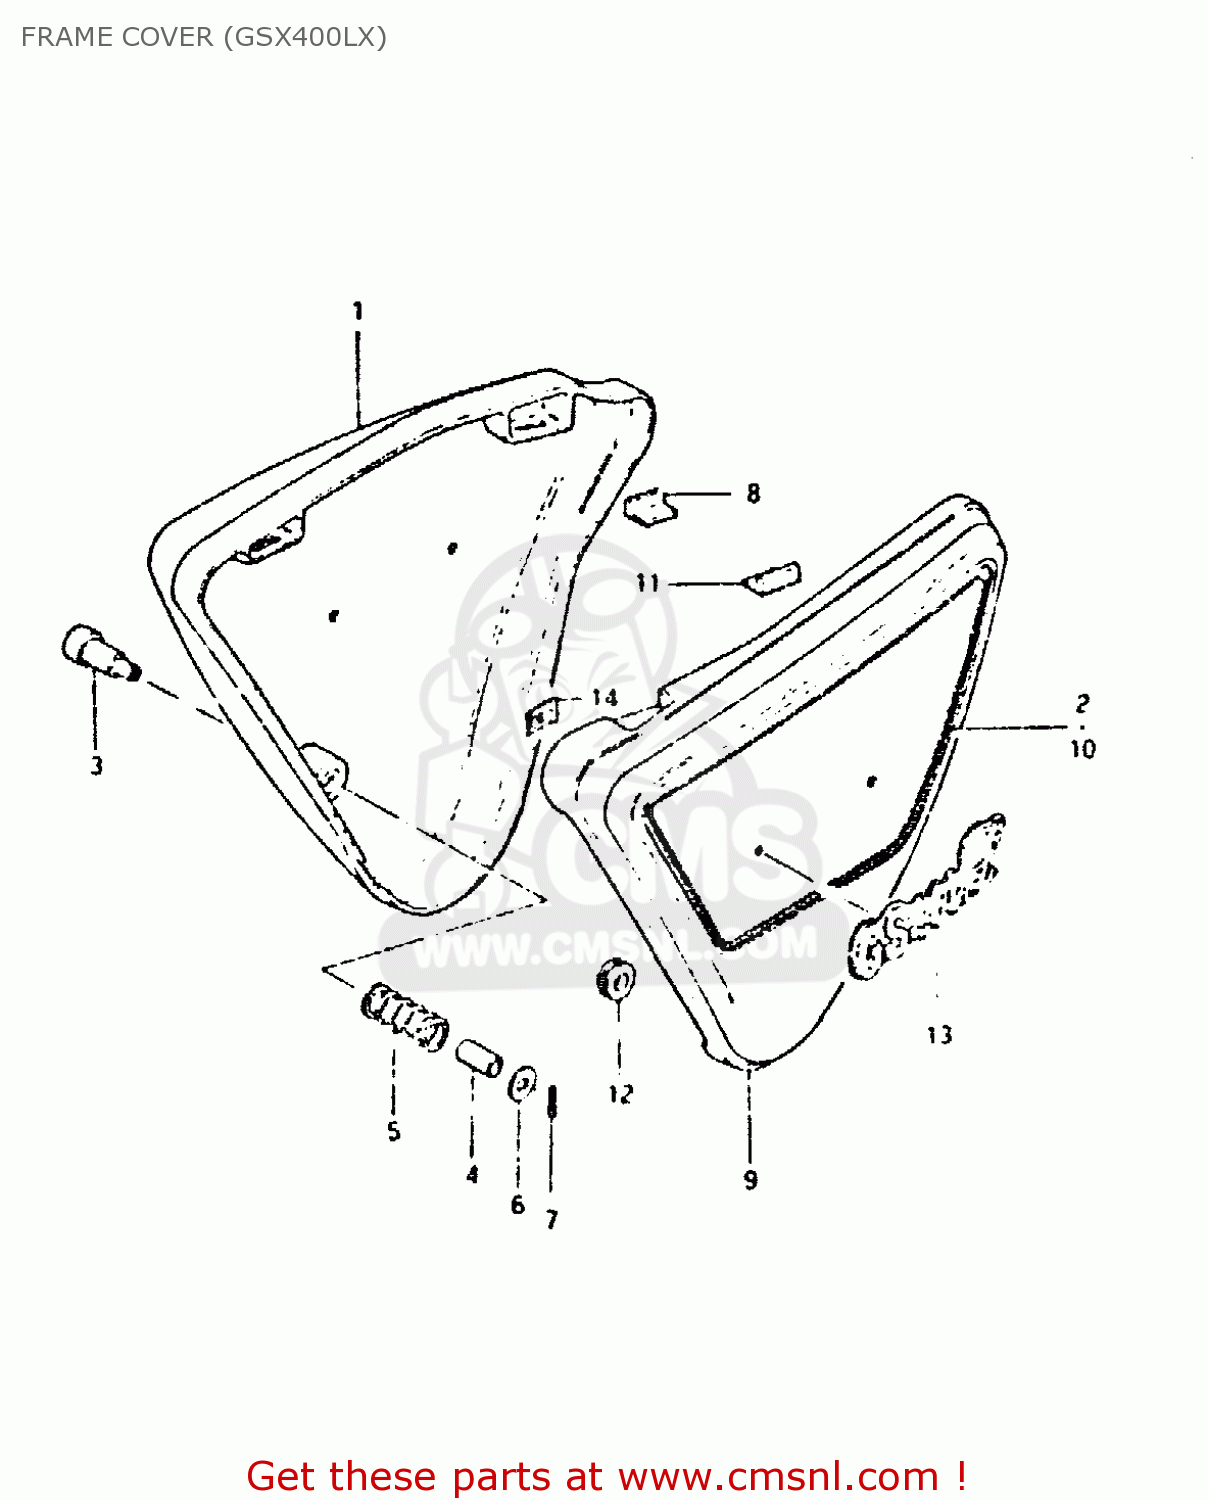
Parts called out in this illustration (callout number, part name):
1	COVER,FRAME,RIGHT
2	TAPE SET,FRAME COVER,RIGHT
3	KNOB,FRAME COVER
4	SPACER(14.9X17.3X13.5)
5	SPRING
6	WASHER (6.5X24X1.6)
7	PIN,SPRING(2.5X18)
8	CUSHION,FRAME COVER
9	COVER,FRAME,LEFT
10	TAPE SET,FRAME COVER,LEFT
11	CUSHION,FRAME COVER
12	CUSHION
13	EMBLEM
14	NUT
